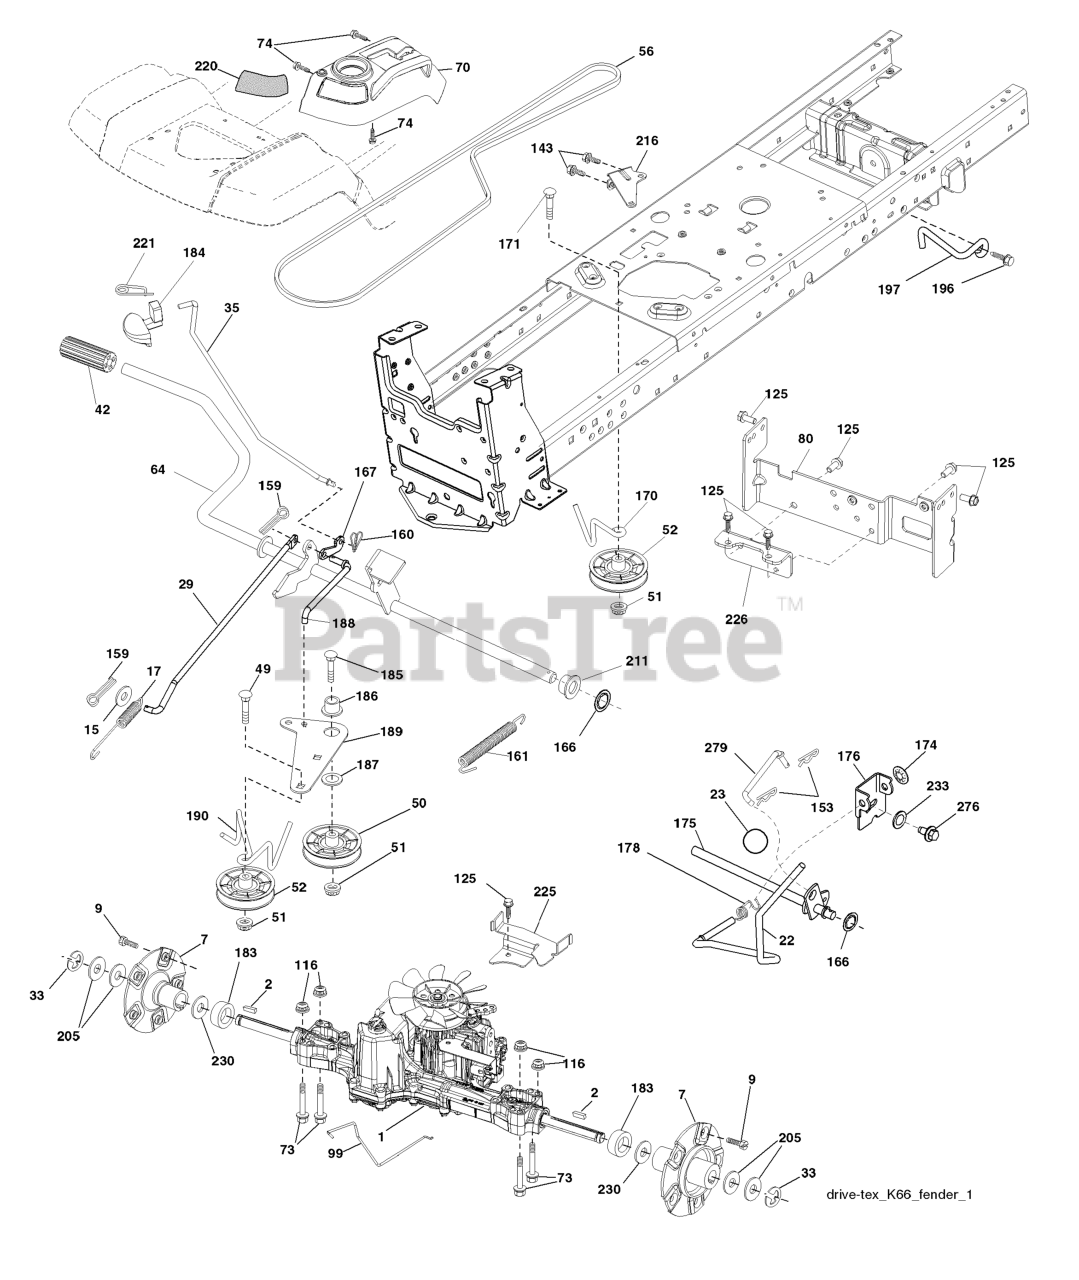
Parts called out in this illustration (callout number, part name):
1	TRANSAXLE.K66.AD.FCH.TG
2	KEY 1/4 X 2.5
7	HUB.ASM.WHEEL.REAR.23"TEX
9	HUB BOLT
15	WASHER
17	SPRING.BRAKE.K46
22	ROD.SHIFT.FENDER.STGT.
23	KNOB.DELUXE.(PISTOL.GRIP).BLAC
29	ROD.BRAKE.K66
33	E RING HYT
35	ROD.BRAKE.PARKING.GT.H
42	PEDAL COVER T
50	IDLER.FLAT.910.OFFSET
51	NUT LOCK FLG 3/8-16 UNC
52	IDLER.V-GROOVE.910.OFFSET
64	SHAFT.ASM.PEDAL.BRAKE.
70	RP CONSOLE.ASM.HYDO.HUSQ.
73	BOLT HEX 5/16-18 GR 5
74	SCREW.HI-LO.CONSOLE
80	STRAP.TORQUE.K66
99	ROD.SPRING.BYPASS.K66.GT.Z
116	NUT LOCK HEX FLANGE 5/16-18
125	SCREW
143	Screw 5/16-18 x 1/2
153	RETAINER M
159	COTTER PIN
160	RETAINER CLIP
161	SPRING, RETURN LT
166	NUT.PUSH.625.2006
167	LATCH.BRAKE.SPRING
170	KEEPER.V-IDLER.CENTER.
171	BOLT
174	NUT.PUSH.500.2006
175	SHAFT.ASM.SHFT.T2.TLT
176	ARM.CLEVIS.ROD.SHIFT
178	SPRING.SHIFT.GT2006
183	SPACER.AXLE.HG.TEX
184	HANDLE.PARKG.BRK.HUSQ X667
185	BOLT
186	SPACER.RETAINER
187	WASHER 12/32X2X10GA
188	RP.LINK.CLUTCH.GROUND.DRIVE
189	BELLCRANK.GROUND.DRIVE.TEX.
190	KEEPER.BELLCRANK.DRIVE
196	SCREW 3/8-16X1
197	BRKT.ANIT-ROTATION.CLUTCH
211	BUSHING.SHAFT.BRAKE.HAND
216	BRACKET.PULLEY.IDLER.W/TEX
220	REFLECTOR.RH.TEX GT
221	RETAINER.SPRING.CLIP.H
225	KEEPER.BELT.TRANSAXLE.K66
226	BRACKET.MOUNT.TORQUE.K66.TG
233	WASHER SERRATED
276	BOLT FIN HEX 7/16-14 X 1
279	LINK.ASM.SHIFT.FENDER.K66
